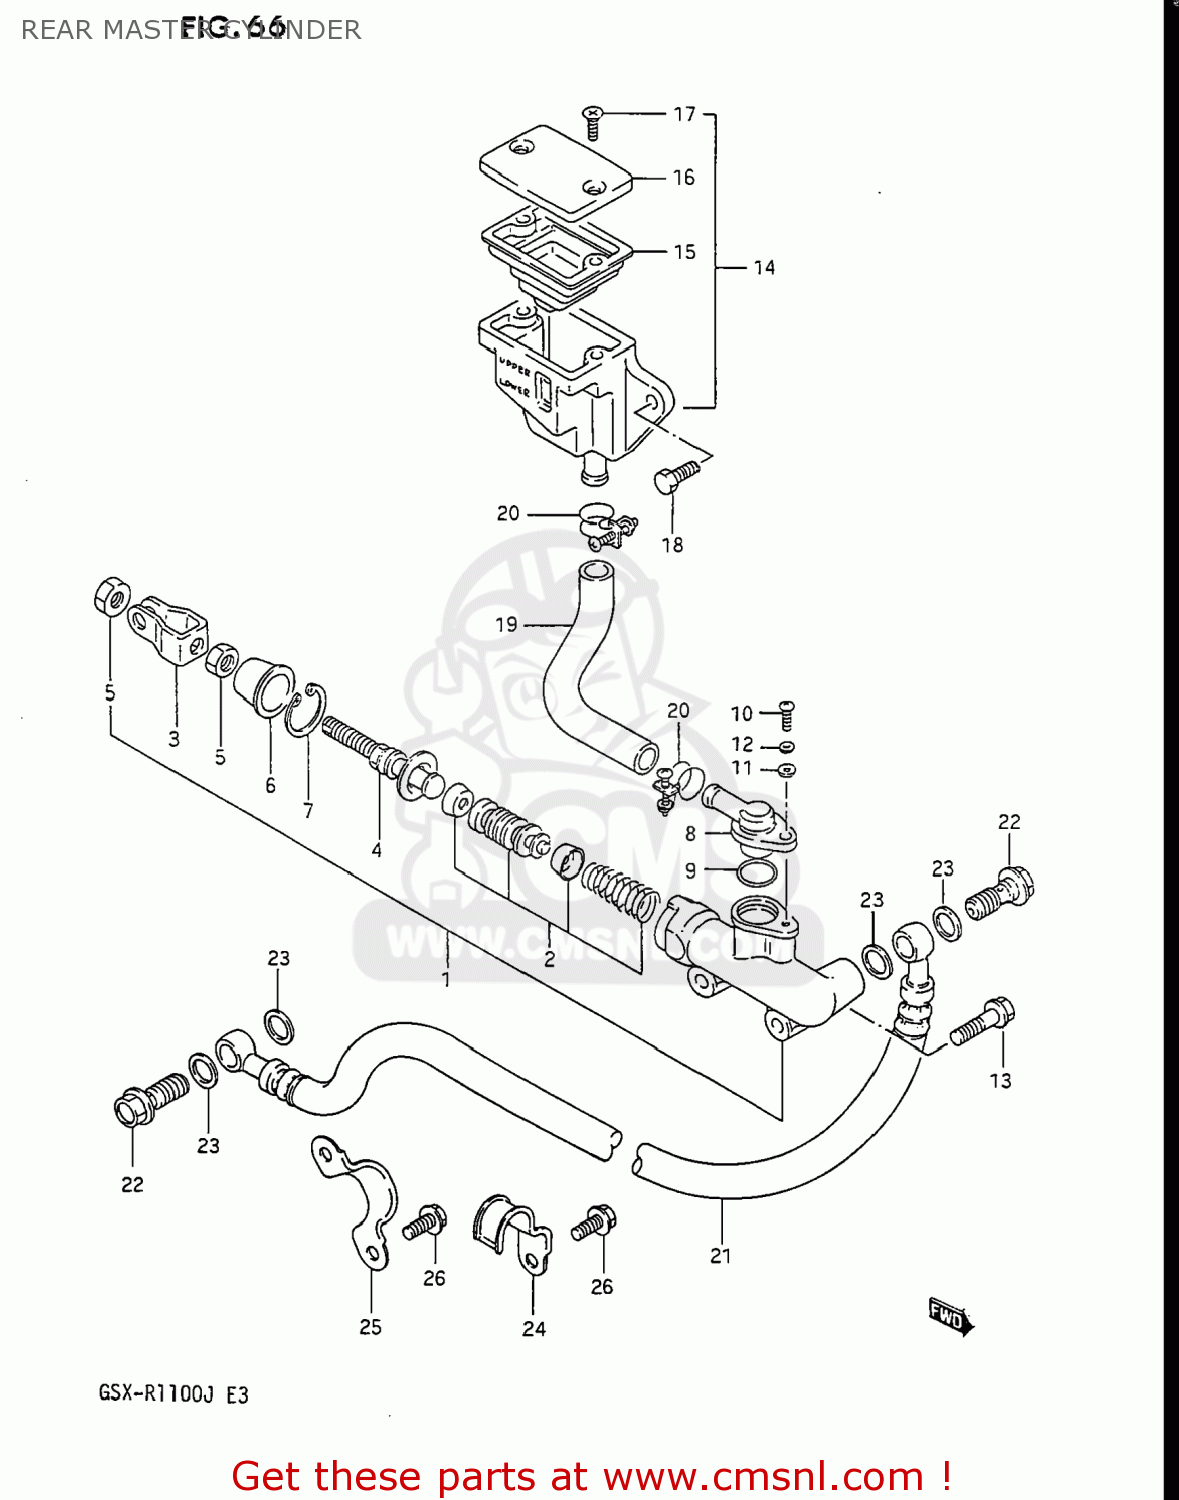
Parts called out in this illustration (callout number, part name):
1	CYLINDER ASSEMBLY,REAR MASTER
2	PISTON/CUP SET
3	YOKE
4	ROD,PUSH
5	NUT
6	BOOT
7	CIRCLIP
8	CONNECTOR
9	O RING
10	SCREW
11	WASHER
12	LOCK WASHER
13	BOLT 6X23
14	TANK ASSEMBLY,RESERVOIR
15	DIAPHRAGM
16	CAP
17	SCREW
18	BOLT
19	HOSE,RESERVOIR TANK
20	CLAMP
21	HOSE,REAR BRAKE
22	BOLT UNION
23	WASHER(10X15X1.5)
24	CLAMP,REAR BRAKE HOSE NO
25	CLAMP,REAR BRAKE HOSE
26	BOLT
